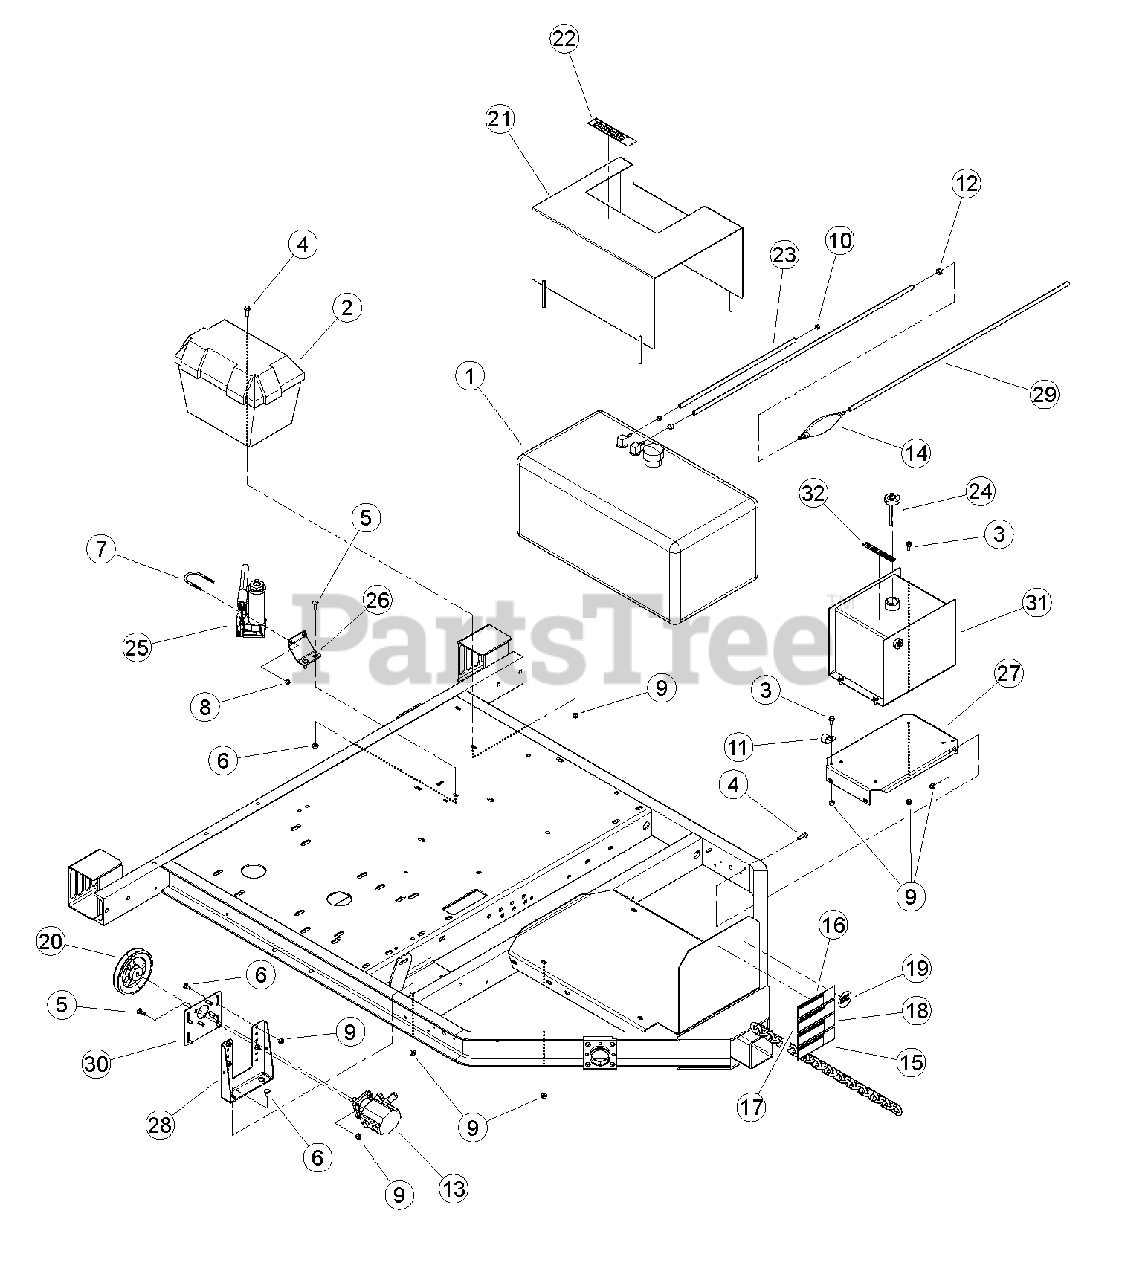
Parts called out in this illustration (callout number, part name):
1	TANK, 19 GAL FUEL
2	BOX, PLASTIC BATTERY
3	BOLT, 5/16 X 3/4 FLANGE NC
4	BOLT, 5/16 X 1 FLANGE NC
5	BOLT, 5/16" X 1" GR5 CRG ZP
6	BOLT, 5/16 X 3/4 GR5 CRG NC ZP
7	U-BOLT, 1/4 X 1-1/2 PIPE
8	NUT, 1/4-20 NYLOCK-FLANGE
9	NUT, 5/16-18 NYLOCK-FLANGE
10	CLAMP, 15/32 SPRING
11	CLAMP, 1" COATED METAL
12	CLAMP, 9/16 SPRING
13	PUMP, 2 STAGE CW HI/LO 0.605 DISP.
14	PUMP, HAND PRIMER
15	DECAL, SAFETY CHAINS
16	DECAL, TRAILER ELECTRICAL
17	DECAL, CHECK WHEELS
18	DECAL, SAFE COUPLING
19	DECAL, NATM COMPLIANCE
20	PULLEY, 5.6 - 1/2" BORE FHP B
21	ASSEMBLY, FUEL TANK CLAMP W/ DECALS
22	DECAL, DIESEL FUEL
23	HOSE, 76" FUEL RETURN
24	CAP, HYDRAULIC W/ DIPSTICK
25	JACK, HYDRAULIC 2 TON
26	PLATE, JACK MOUNT
27	SHEET, TANK MOUNT
28	BRACKET, MOUNT HYDRAULIC PUMP
29	HOSE, 38" FUEL
30	PLATE, PUMP MOUNT
31	ASSEMBLY, HYDRAULIC TANK 3.25 GAL
32	DECAL, HYDRAULIC FLUID
